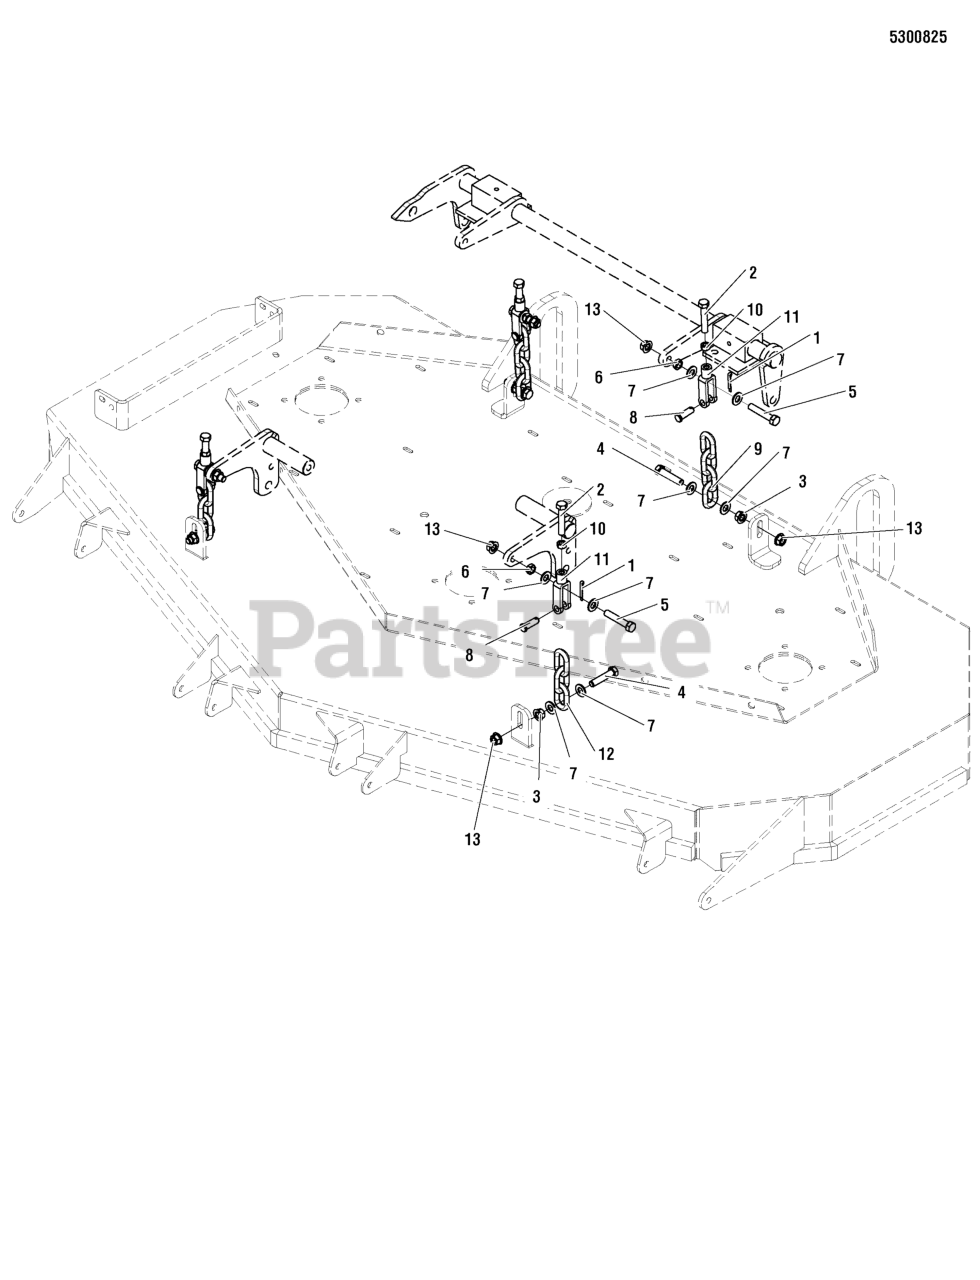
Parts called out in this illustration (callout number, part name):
1	PIN, COTTER, 1/8" X 3/4
2	BOLT, 5/16-18 X 2" GD5 TFL
3	NUT, 3/8-16 HEX SERRATED FLANGE
4	BOLT, 3/8-16 X 1-3/4" GD5 CZ
5	BOLT, 3/8-16 X 2, GD5, CZ
6	NUT, 3/8-16 HEX JAM
7	WASHER, 3/8 SAE
8	PIN, CLEVIS, 3/8" X 1-1/8"
9	CHAIN, 5/16" GD30, 4 LINKS
10	NUT, 5/16-18 HEX
11	CLEVIS, 5/16-18, 3/8" PIN HOLE
12	CHAIN, 5/16" GD30, 3 LINKS
13	NUT, 3/8-16 HEX NYLOCK FLANGE
